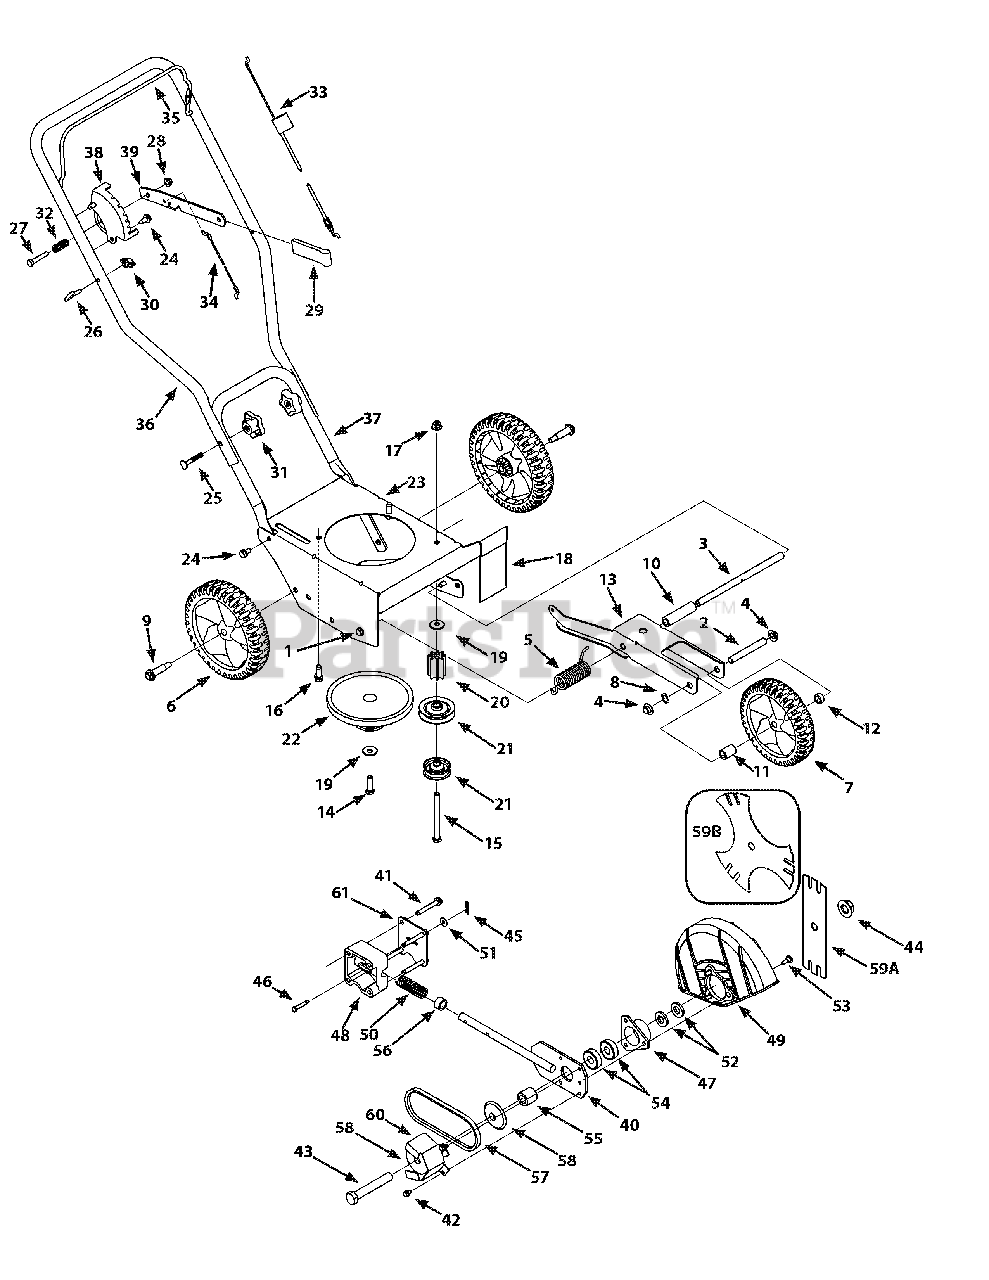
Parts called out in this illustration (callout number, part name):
1	Hex Head Screw 3/8-16
2	Axle .50 x 3.8
3	Axle .50 x 9.25
4	Push Cap 1/2" rod
5	Torsion Spring
6	Wheel 8x1.8
7	Wheel 7x1.8
8	Wave Washer
9	Shoulder Screw, 3/8-16
10	Spacer
11	Spacer, .525 x .775 x .1125
12	Spacer, .525 x .775 x .3125
14	Screw 3/8-24
15	Screw 3/8-16
16	Screw, 3/8-16
17	Flange Lock Nut, 3/8-16
18	Debris Guard
19	Bell Washer, .396 x 1.140
20	Pulley Mount Spacer
21	Flat Idler Pulley, 2.5 OD
22	Combination Flywheel Pulley
24	Hex Screw, 5/16-12
25	Carriage Bolt, 5/16-18
26	Rope Guide (Eye Bolt)
27	Hex Screw, 5/16-18
28	Lock Flange Nut, 5/16-18
30	Wing Nut
31	Hand Knob
32	Compression Spring
33	Control Cable
34	Wheel Adjustment Cable
36	Upper Handle
37	Lower Handle
40	Blade Plate Assembly
41	Hex Screw, 5/16-18
42	Self-tapping Screw, 1/4-20
43	Hex Screw, 5/8-18
44	Flange Nut, 5/8-18
45	Cotter Pin
46	Clevis Pin
47	Bearing Cup
48	Bearing Block
49	Blade Guard
50	Compression Spring
51	Flat Washer, .260 x.72
52	Flat Washer .635x1.24x.181
53	Shoulder Screw
54	Bearing, .625 ID x 1.57 OD
55	Spacer, .63 x 1.12 x 1.06
56	Spacer, .64 x.88 x .50
58	Sheave
59A	Edger Blade
59B	Tri-Star Blade
60	Belt Guard
61	Cover Plate
